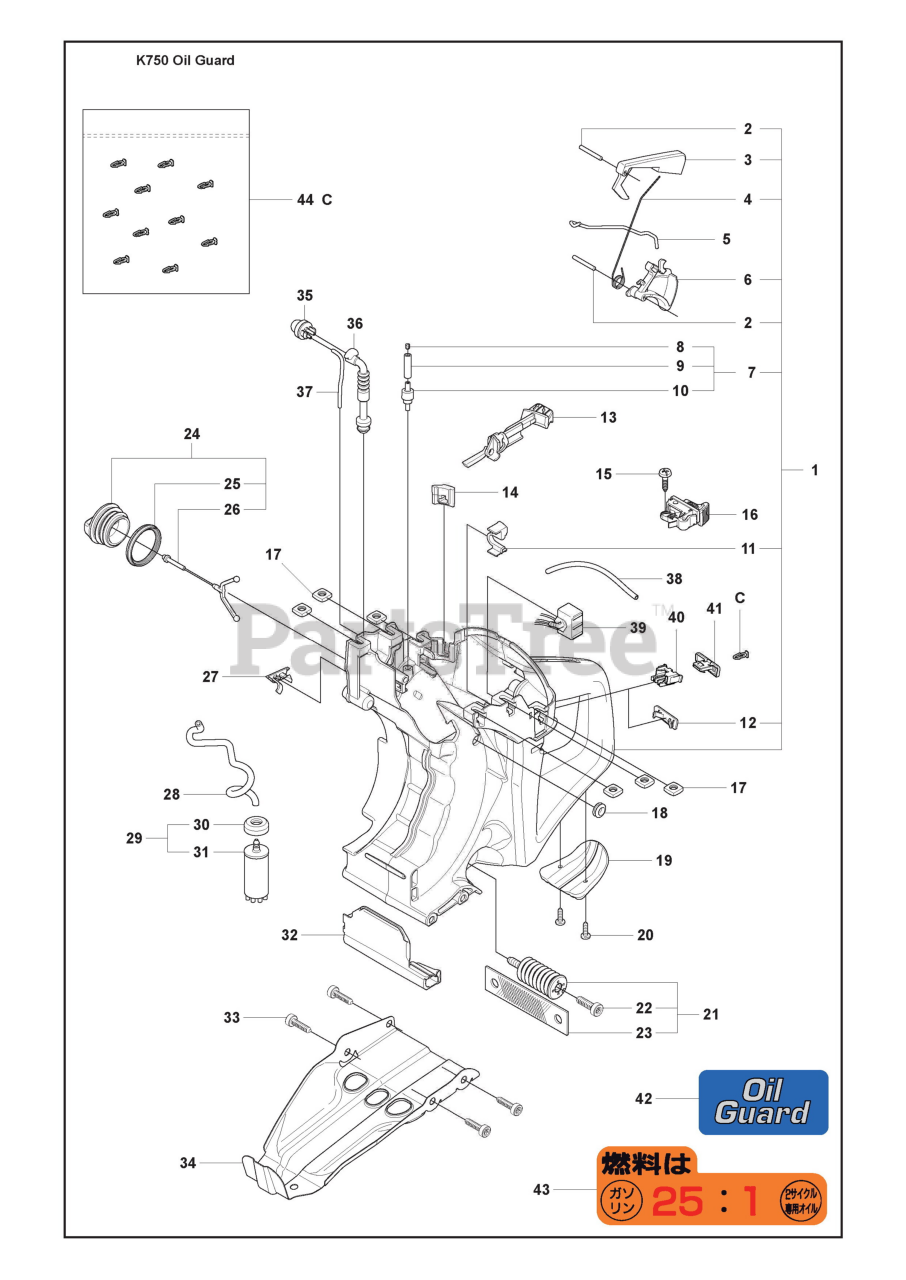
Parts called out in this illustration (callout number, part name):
1	FUEL TANK
2	PARALLEL PIN
3	THROTTLE LOCKOUT
4	SPRING
5	THROTTLE ROD
6	THROTTLE TRIGGER
7	TANK VENT ASSY
8	SINTER PLUG
13	CHOKE CONTROL
16	STOP SWITCH
18	CABLE GROMMET
19	GROUND SUPPORT
21	AV-ELEMENT
24	TANK CAP ASSY
26	TANK CAP HOLDER
28	FUEL HOSE
29	FUEL FILTER
30	HOSE CLAMP
31	FUEL FILTER
32	HEAT SHIELD
34	BASE PLATE
35	PRIMER HOUSING
36	FUEL HOSE
37	FUEL HOSE
38	FUEL HOSE
39	ELECTRONIC BOX
40	HOUSING
41	SWITCH
42	LABEL
43	LABEL
44	CUP SPRING
